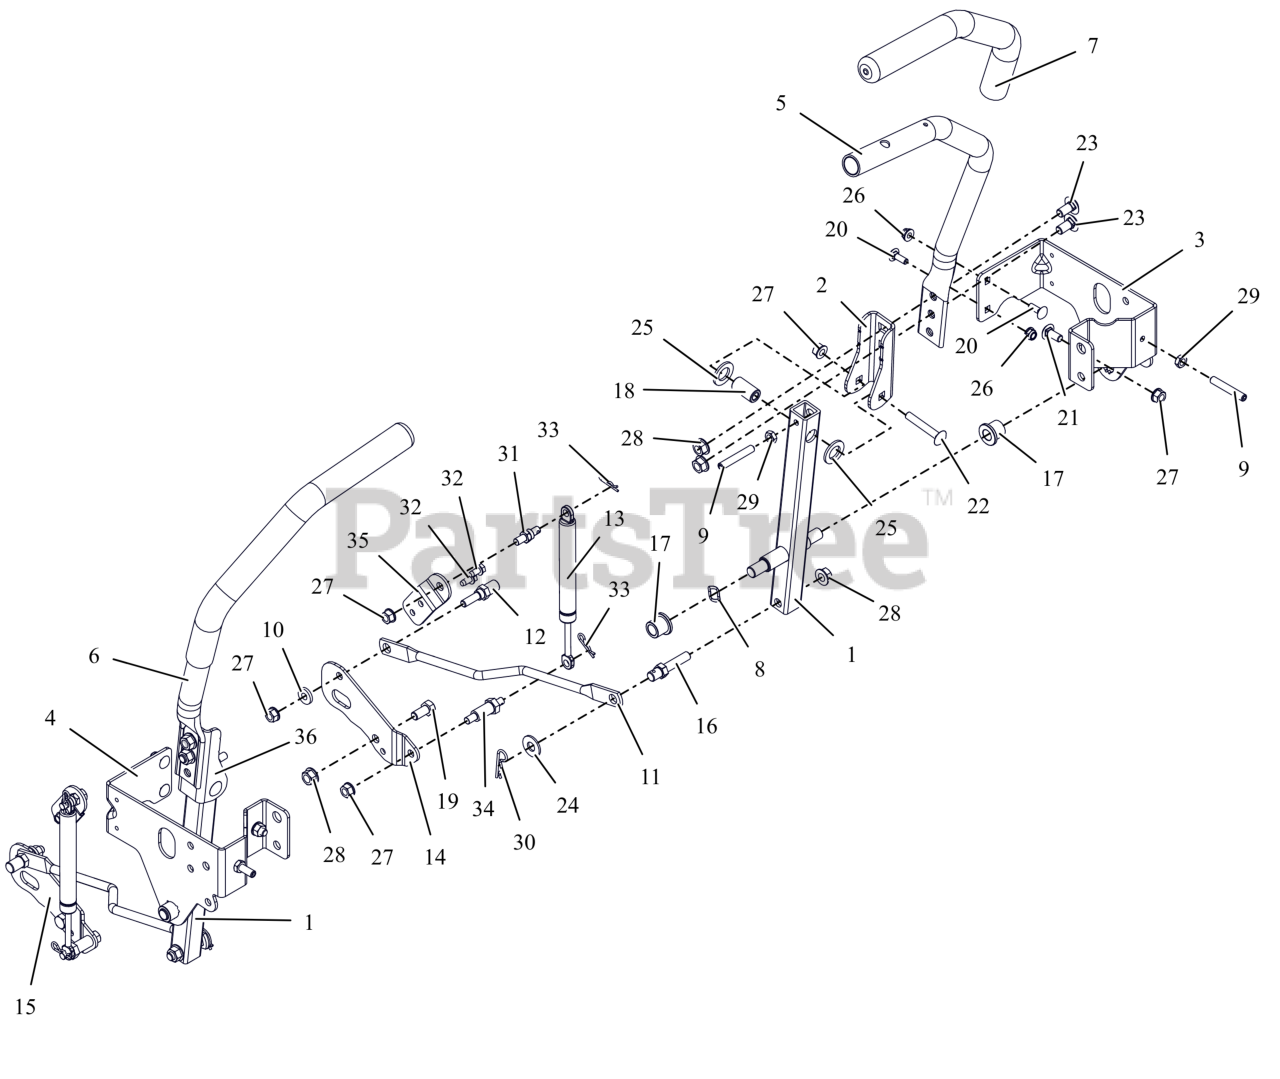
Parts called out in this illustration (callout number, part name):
1	WLDMT, LOWER CONTROL ARM (BLACK)
2	ARM, CONTROL -UPPER
3	BRKT, SPEED ADJ/SEAT PIVOT-LH (BLACK)
4	BRKT, SPEED ADJ/SEAT PIVOT-RH (BLACK)
5	WLDMT, CONTROL HANDLE -LH (BLACK)
6	WLDMT, CONTROL HANDLE - RH (BLACK)
7	GRIP, HANDLEBAR 15" FOAM
8	WAVE WASHER .531X.781X.125FH
9	SCR-SET, .312-18X2.000 SS
10	BSHG-FLG .316X.430X.225X.750
11	LINKAGE, STEERING
12	STUD, STEERING LINK-REAR
13	DAMPER, STRAIGHT MOUNT
14	PLATE, DAMPER RH
15	PLATE, DAMPER
16	STUD, STEERING LINK -FRONT
17	BHSG-FLG .500X.750X.750X.125
18	BSHG, -SLV .342 X .627 X 1.171
19	BLT,HEX .38-16X.75 G5 ZCC
20	BLT, RHSN .25-20X.750 G5 ZCC
21	BLT, RHSSN.31-18X.750 G5 ZCC
22	BLT, RHSSN .31-18X2.00 G5 ZCC
23	BTL,RHSSN .375-16 X 0.75 G5 FPB
24	WSHR,FLT .438X1.00X.083 ZCC
25	WSHR, FRICTION
26	NUT,NYL-FLG .25-20 GF ZCC
27	NUT,LK-CTR-FLG .31-18 GF ZCC
28	NUT-LK-CTR-FLG .375-16 GF ZCC
29	NUT-JAM .312-18 G2 ZCC
30	PIN, HAIR #203 .09X1.50 ZCC
31	COUPLER, DAMPER MOUNT
32	SCR-TAP .25-20X.50 HWH ZCC
33	PIN, HAIR #213 .08X1.19 ZCC
34	COUPLER, DAMPER MOUNT (LOWER)
35	PLATE, DAMPER TOP MOUNTING (BLACK)
36	ARM, CONTROL -UPPER (BLACK)
